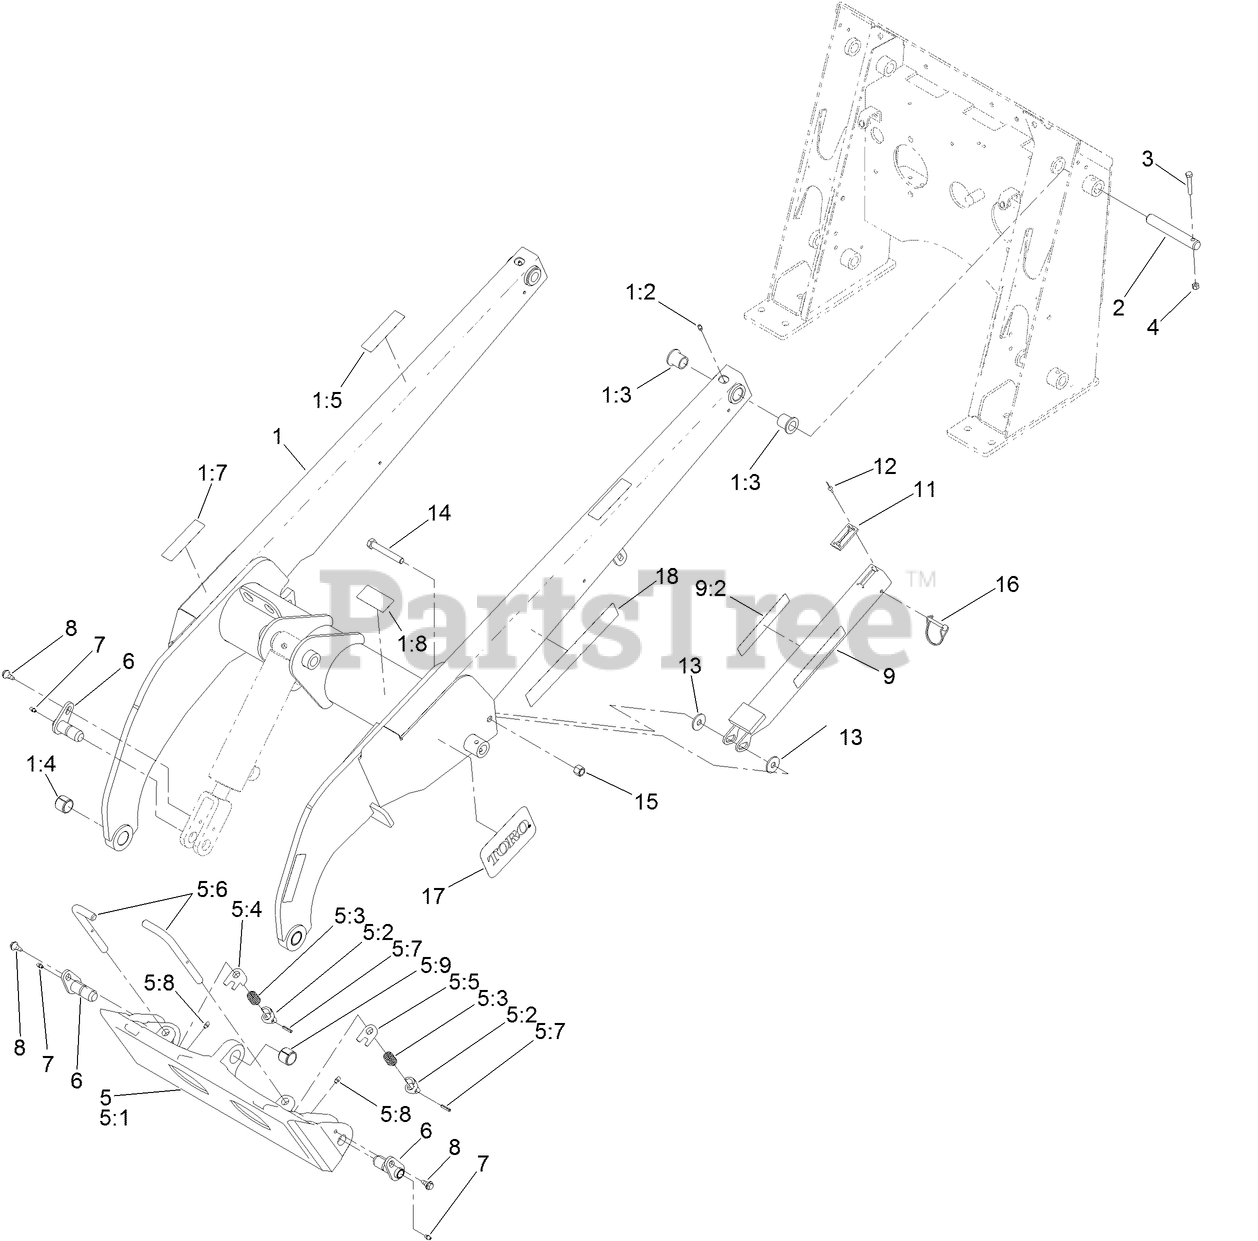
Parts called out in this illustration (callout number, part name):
1	LOADER ARM ASM
1:2	FITTING-GREASE
1:3	BUSHING
1:4	BUSHING-TENSION
1:5	DECAL-WARNING, PINCH
1:7	DECAL-CAUTION
1:8	DECAL-NO RIDER
2	PIN-LOCKING
3	SCREW-HH
4	NUT-LOCK, NI
5	QUICK ATTACH ASM
5:1	MOUNT-QTACH
5:3	SPRING-COMPRESSION
5:4	STOP-RH
5:5	STOP-LH
5:6	PIN-LOCKING
5:7	PIN-GROOVED
5:8	FITTING-GREASE
5:9	BUSHING-TENSION
6	PIN-PIVOT
7	FITTING-GREASE
8	BOLT-SHOULDER
9	LOCKING ARM ASM
9:2	DECAL-DANGER
11	STOP-RUBBER
12	RIVET
13	WASHER-RUBBER
14	SCREW-HH
15	NUT-LOCK, NI
16	PIN-HITCH
